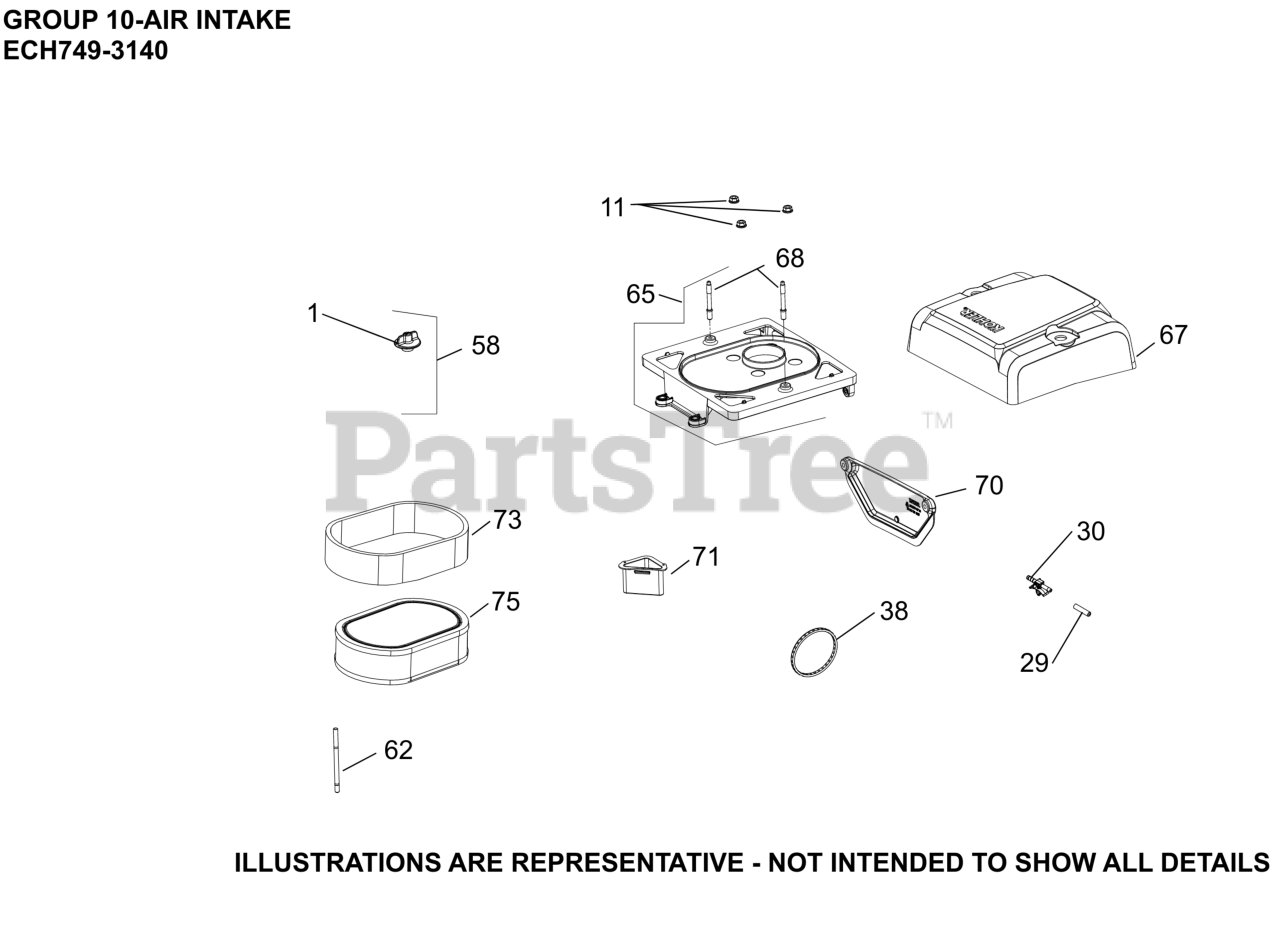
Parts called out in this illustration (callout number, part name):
1	KNOB, COVER
11	NUT, FLG M6X1.0
29	CAP, MASKING
30	CONNECTOR, EVAPORATIVE
38	O-RING (HDAC SEAL-EFI)
58	KIT, KNOB W/SEAL
65	BASE, AIR CLEANER ASSEMBLY (LPAC-ETB)
67	COVER, AIR CLEANER (LPAC - ETB)
68	STUD, 6.3 X 1.69 HI-LO / M6 X 1
70	COVER, ETB (HORIZONTAL LPAC)
71	DUCT, AIR (LPAC - ETB)
73	ELEMENT, PRE-CLEANER
75	ELEMENT, AIR FILTER (ETB)
NI	BRACKET, LPAC SUPPORT (ETB)
NI	SCREW, HEAVY HEX FLANGE
NI	HOSE, EVAPORATIVE
NI	HOSE, ASSEMBLY
NI	HOSE EVAPORATIVE (WALBRO)
NI	SLEEVE, ANTI ABRASION
